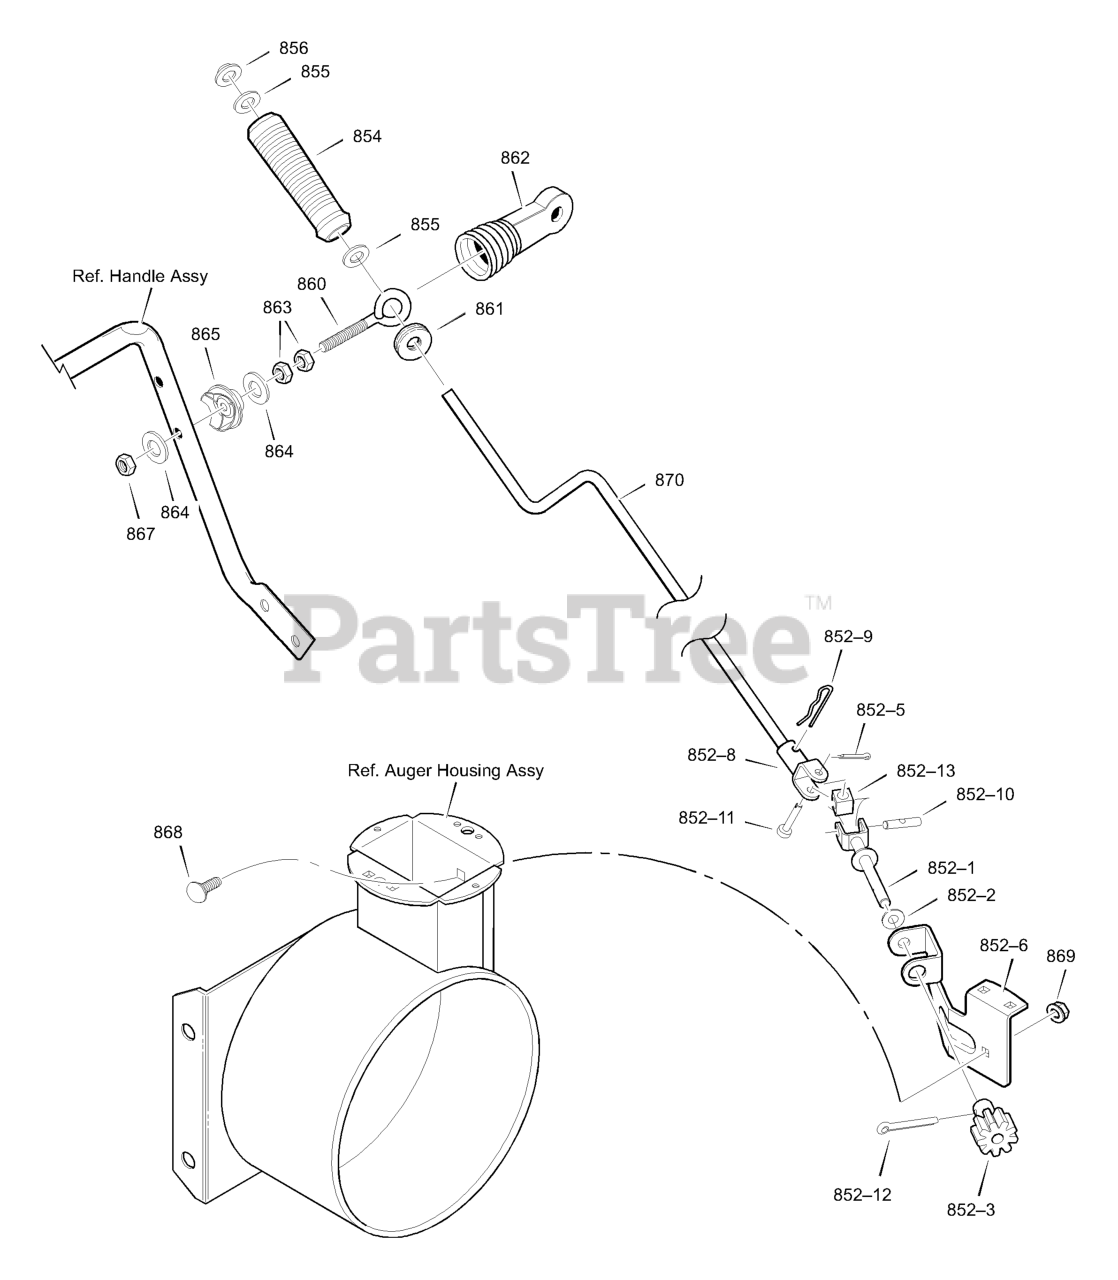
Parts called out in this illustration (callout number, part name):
852-1	ASSEMBLY, YOKE & ROD
852-2	WASHER, CURVED SPRING
852-3	GEAR, CHUTE ROTATION 9T
852-5	PIN, COTTER
852-6	BRACKET, GEAR MOUNT
852-7	PIN, COTTER
852-8	ASSEMBLY, YOKE ADAPTER YZ
852-9	PIN, HAIR
852-10	PIN, UNIVERSAL JOINT
852-11	PIN, CLEVIS
852-12	PIN, COTTER
852-13	HOUSING, UNIVERSAL
854	KNOB, SLEEVE
855	FLATWASHER
856	NUT, PUSH ON 3/8"
860	EYE BOLT 3/8-16X6.00
861	GROMMET, EYE BOLT
862	BOOT, EYE BOLT
863	NUT, 3/8-16 HEXJAM
864	FLATWASHER .406X.81X.066
865	ADAPTER, BOOT
866	WASHER, FLAT
867	NUT, 3/8-16 HEXNYL
868	BOLT, CARRIAGE 1/4-20 X 1.00
869	NUT, 1/4-20
870	CRANK, ASSY CHUTE
